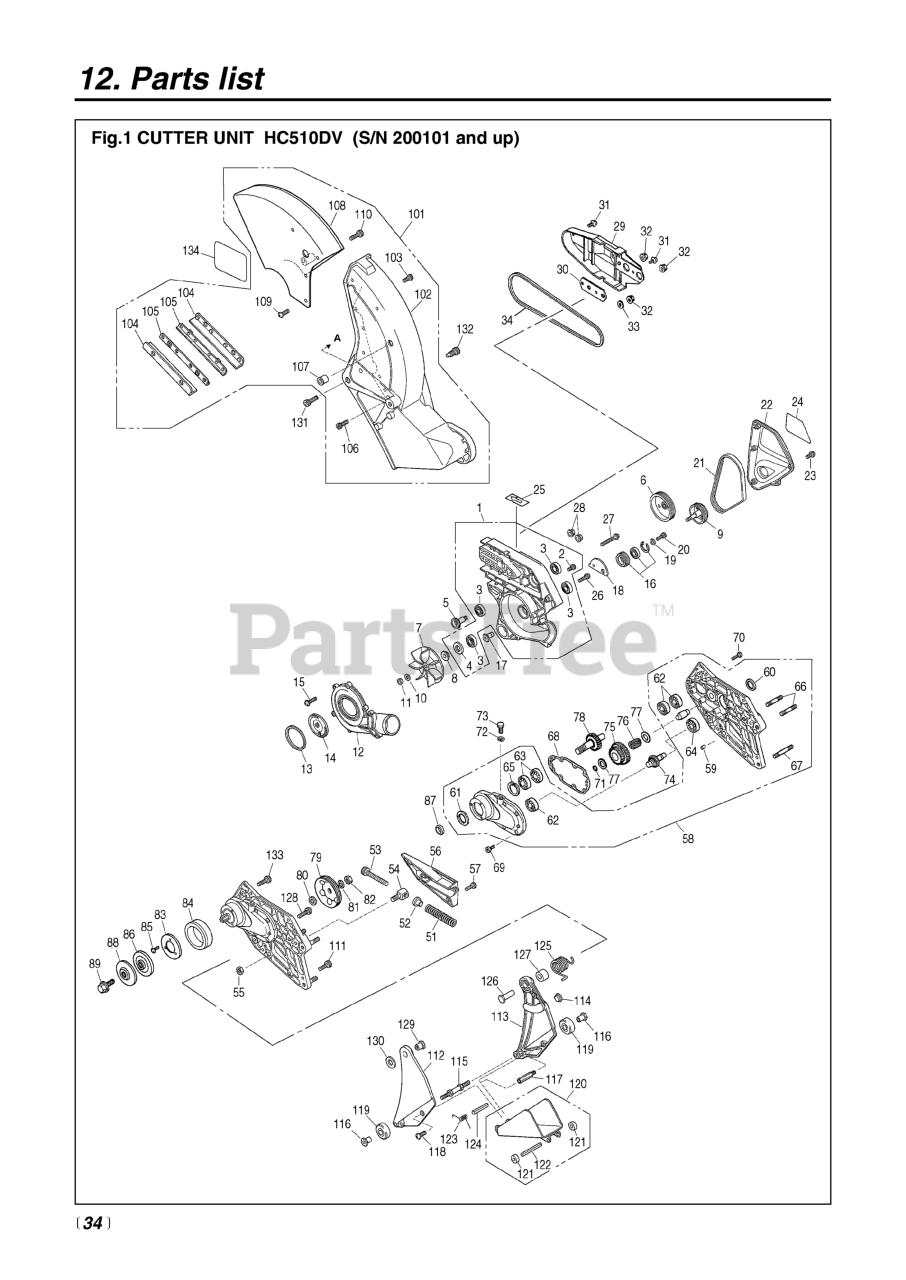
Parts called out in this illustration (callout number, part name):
1	CASE COMP
3	BEARING
4	SEAL, OIL
5	SHAFT, INLET
9	SHAFT COMP.
10	WASHER, M8 x 2.3 (RPLS -20823)
11	NUT (RPLS -43230)
12	COVER, FAN
16	IDLER PULLEY COMP.
17	SHAFT, IDLER
18	CAM PLATE
19	WASHER, M6 X 2.3
22	COVER, BELT
23	SCREW (REPLACES 2616-24320)
28	NUT
29	COVER, PULLEY
31	SCREW
32	NUT
33	WASHER, M8 x 2.3 (RPLS -20823)
54	GUIDE NUT
55	NUT (RPLS -43230)
56	COVER, SPRING
57	SCREW (REPLACES 2616-24320)
58	GEARCASE COMP.
59	PIN, DOWELL
62	BEARING
65	RING, SNAP, M32 x 1.2
74	SHAFT COMP.
75	GEAR COMP.
78	SHAFT COMP.
81	WASHER, M8 x 20
82	NUT (RPLS -43230)
83	PLATE, END
84	END RING
101	COVER ASSY.
102	BLADE COVER
108	COVER, UPPER
109	SCREW (REPLACES 2616-24320)
112	FRONT GUIDE (R)
113	FRONT GUIDE (L)
115	JOINT BOLT
117	JOINT BOLT
118	SCREW
120	SLIDE GUIDE COMP
122	SPRING PIN
123	RETURN SPRING
124	SPRING PIN
125	RETURN SPRING
132	STOPPER BOLT
134	LABEL, CAUTIION
